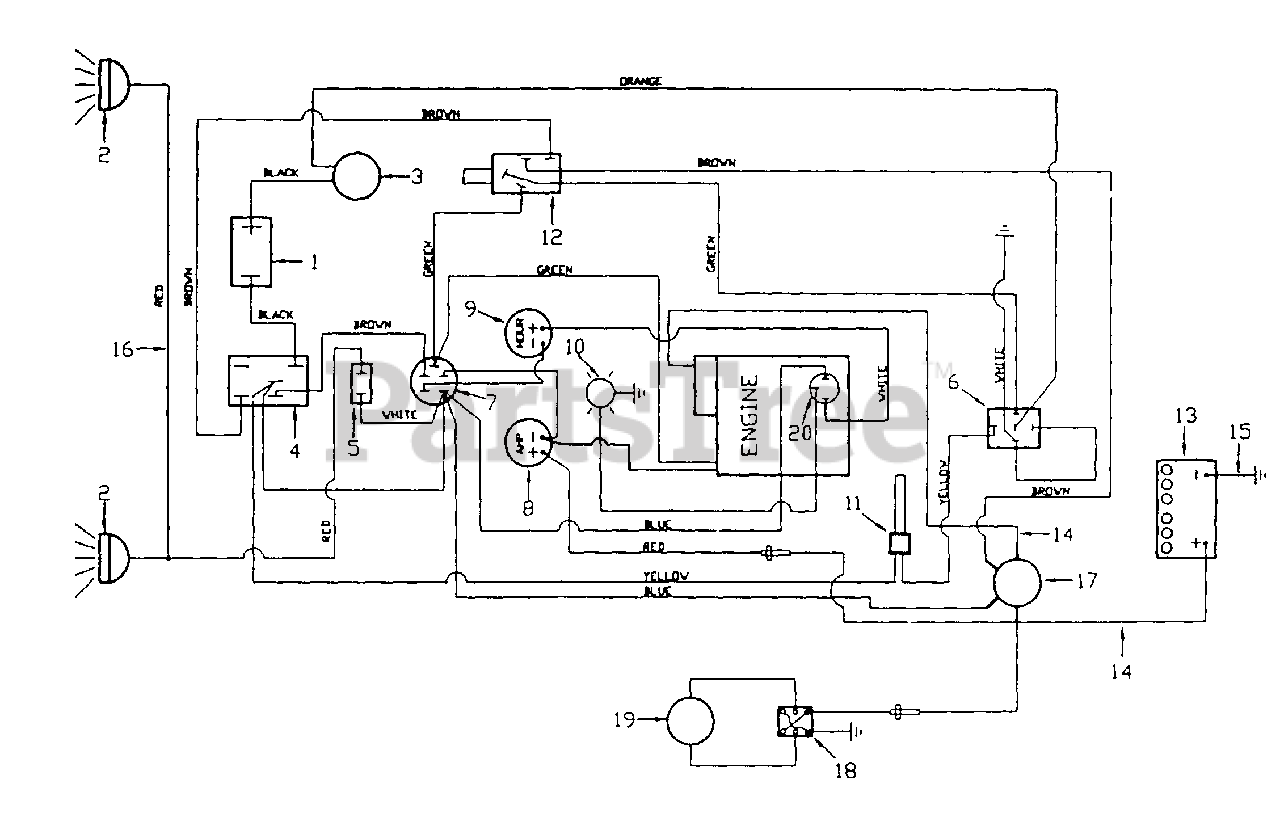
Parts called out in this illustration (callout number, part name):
1	10 Amp Circuit Breaker
2	Headlight Assembly
3	Electric Clutch Assembly
4	PTO Clutch Switch
5	Light Switch
6	Relay
7	Ignition Switch
13	Battery
16	Wire - light to switch
18	3 Position Deck Lift Switch
19	Electric Lift Actuator
20	Oil Sending Unit
